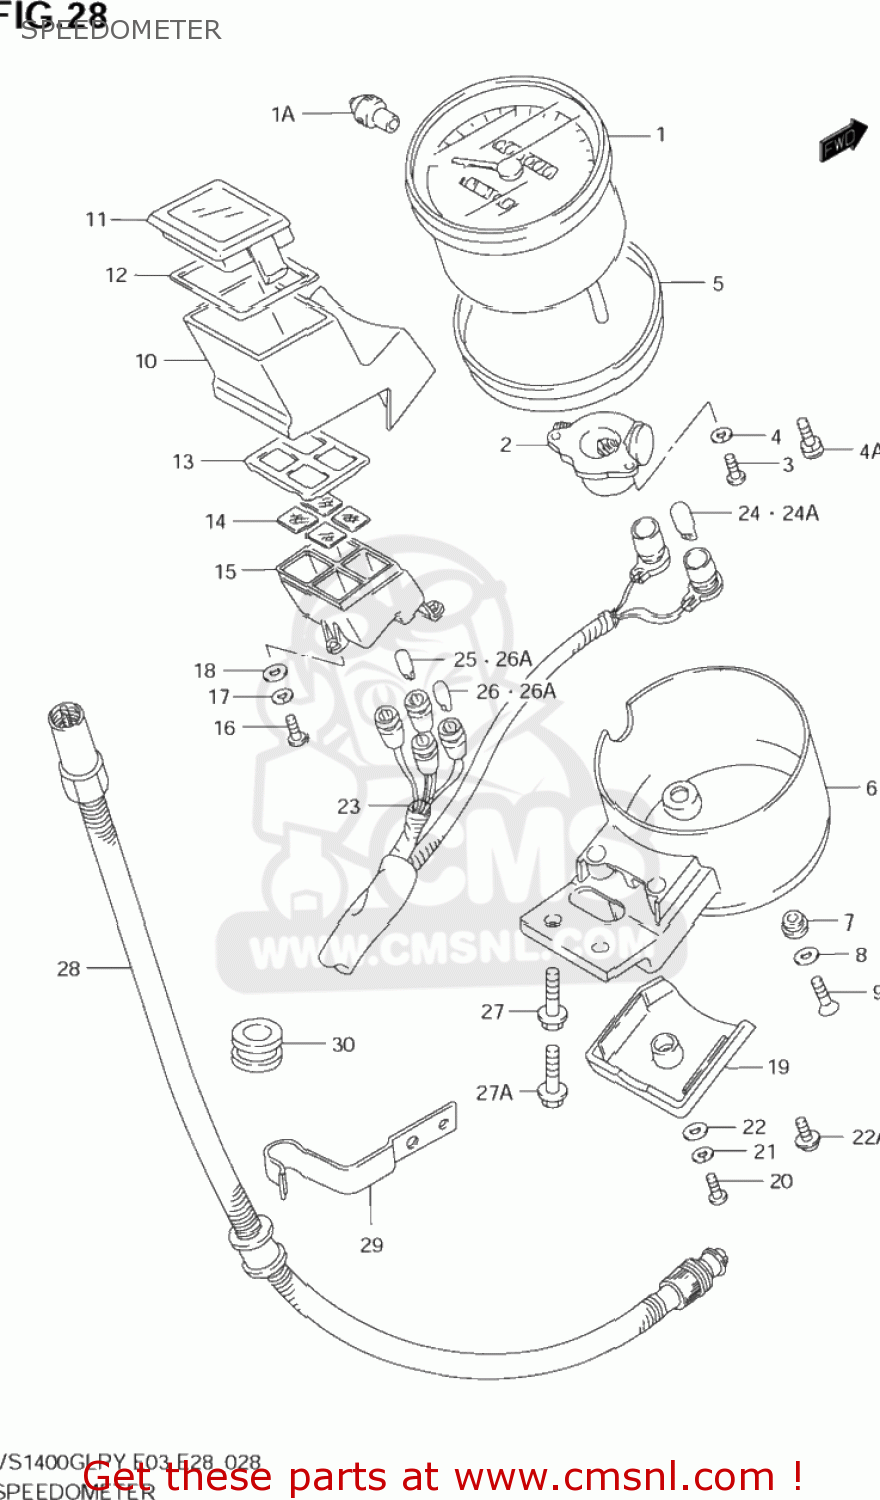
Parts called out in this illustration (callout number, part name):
1	SPEEDOMETER(KILO)
1A	KNOB,TRIP
2	BOX,GEAR
3	SCREW
4	WASHER,LOCK
4A	SCREW
5	CUSHION
6	COVER,METER
7	CUSHION,METER
8	WASHER
9	SCREW
10	BOX,PILOT
11	LENS,PILOT BOX
12	CUSHION
13	PLATE,PILOT LENS
14	LENS SET,PILOT LAMP
15	CASE,PILOT LAMP
16	SCREW
17	WASHER,LOCK
18	WASHER
19	COVER,PILOT BOX
20	SCREW
21	WASHER,LOCK
22	WASHER
22A	SCREW
23	SOCKET,METER
24	BULB(12V3.4W,T10)
24A	BULB(12V3.4W,T10)
25	BULB(12V3W,T6.5)
26	BULB(12V1.7W,T6.5)
26A	BULB(12V1.7W,T6.5)
27	BOLT
27A	SCREW
28	CABLE ASSY,SPEEDOMETER
29	GUIDE,SPEEDOMETER CABLE
30	GROMMET
